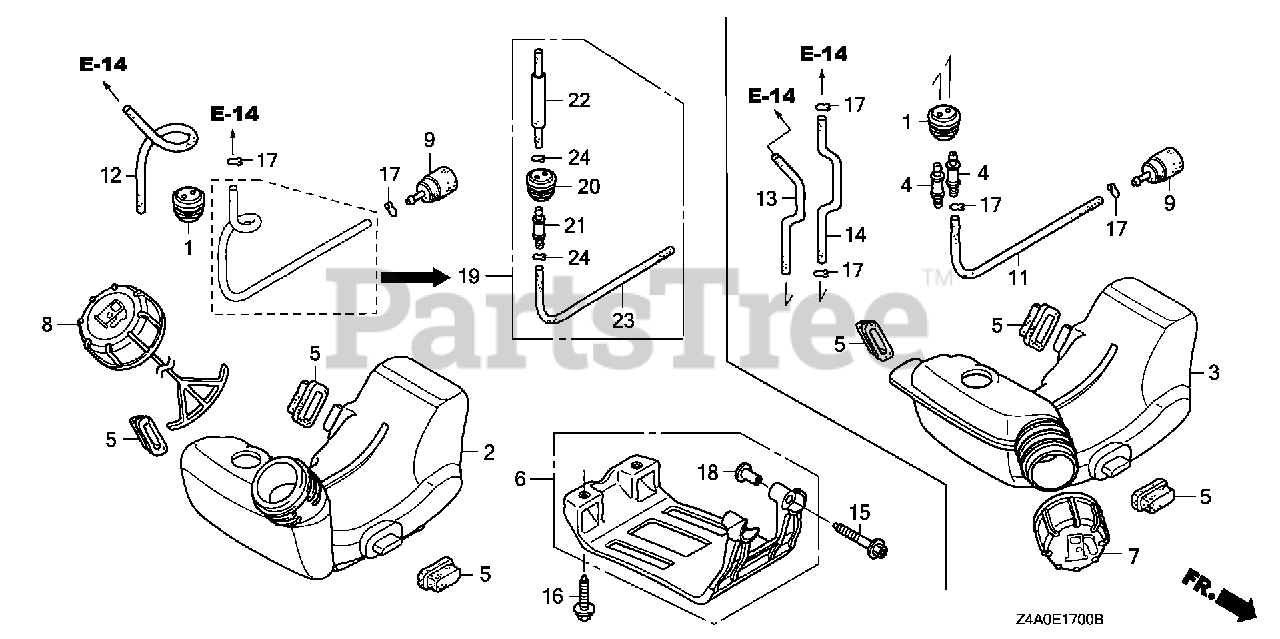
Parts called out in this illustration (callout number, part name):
1	GROMMET, FUEL TUBE
2	TANK, FUEL (FOR U.S.A.)
5	RUBBER, TANK MOUNTING
6	GUARD, TANK
8	CAP ASSY., FUEL TANK
9	FILTER, FUEL
12	TUBE, FUEL RETURN
15	BOLT, SOCKET (5X30)
16	BOLT, SOCKET (5X16)
17	CLIP, TUBE
18	COLLAR, TANK GUARD
19	GROMMET ASSY., FUEL TANK
20	GROMMET, FUEL TUBE
21	FITTING
22	TUBE, FUEL FEED
23	TUBE A, FUEL
24	CLIP, TUBE
